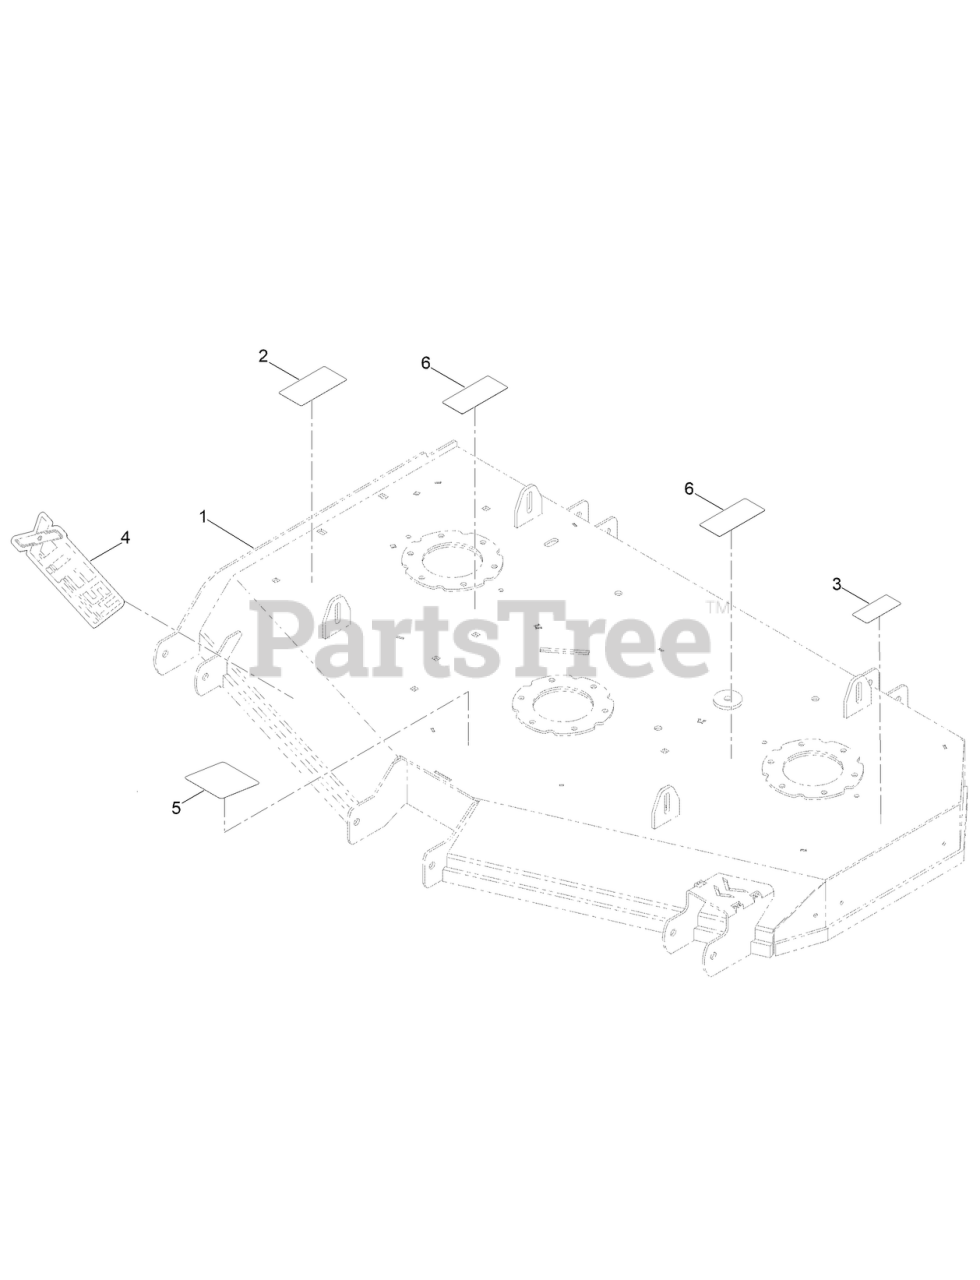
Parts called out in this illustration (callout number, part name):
1	Deck
2	DECAL-DANGER, DECK
3	DECAL-SAFETY BLADE TORQUE
4	DECAL-XTF
5	DECAL-DECK BELT ROUTING
6	DECAL-ROTATING FAN HAZARD
